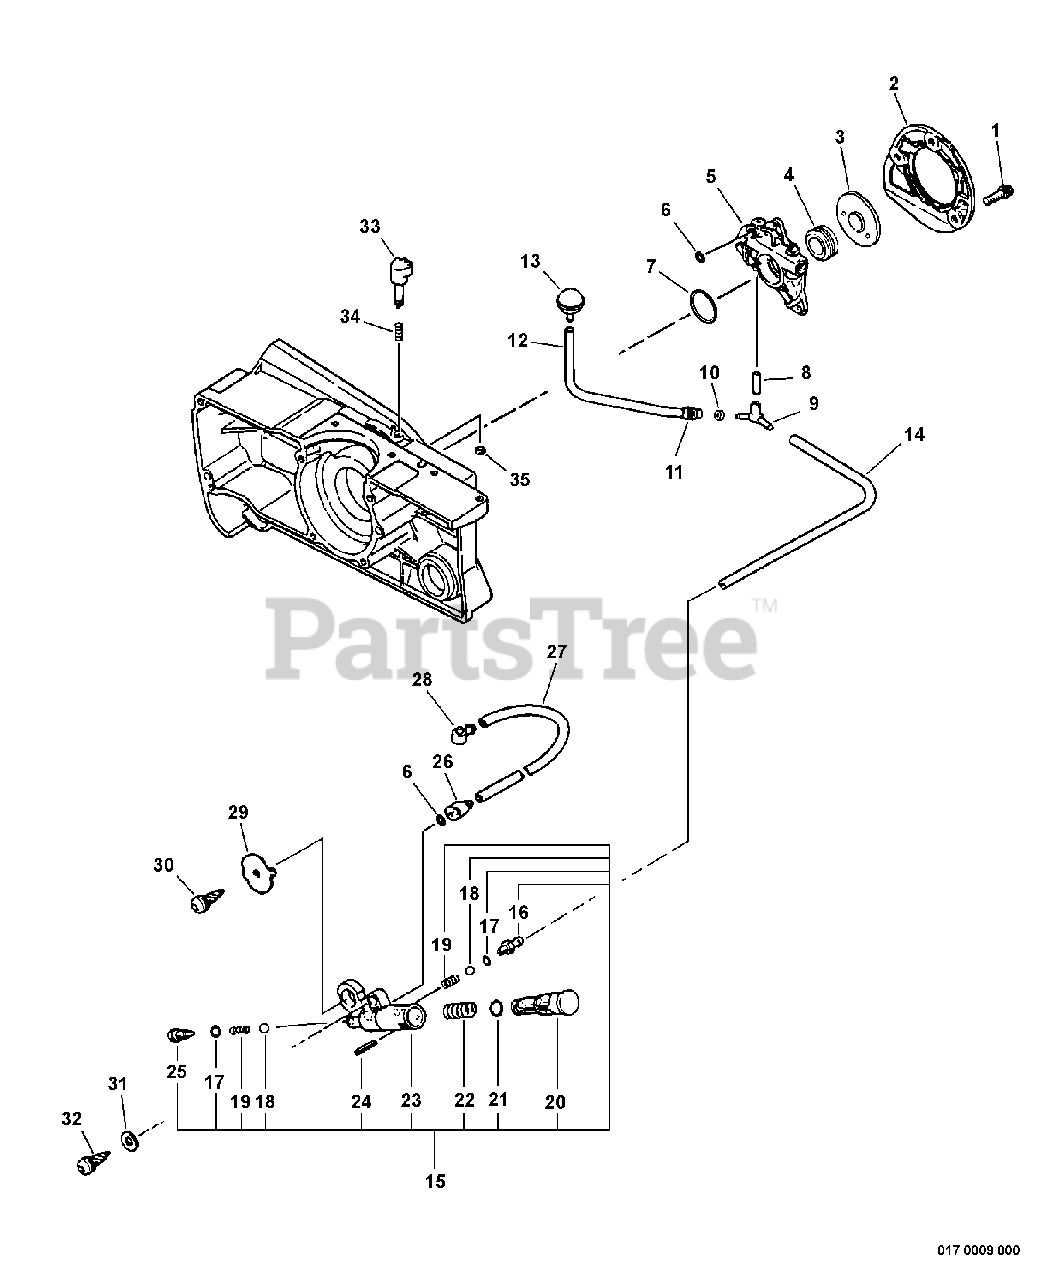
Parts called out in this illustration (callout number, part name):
1	SCREW - 4X12
2	COVER, OIL PUMP
3	WASHER - 12
4	GEAR - WORM
5	AUTO-OILER ASSY
6	O-RING - 3
8	PIPE - 3X6X20 -- BLACK
9	CONNECTOR, PIPE
10	CLIP - 6.5
12	PIPE - OIL
13	FILTER, OIL
14	PIPE - 3X6X200 -- BLACK
15	OIL PUMP ASSY
18	VALVE, BALL
20	PISTON, OIL PUMP
21	O-RING - 7
23	BODY, OIL PUMP
24	PIN - SPRING -- 2X16
25	ADAPTER, OIL PUMP
26	CONNECTOR, PIPE
27	PIPE, OIL - 3X6X125
28	CONNECTOR, PIPE
29	BRACKET, OIL PUMP
30	SCREW - 4X10
31	WASHER - 5
32	SCREW - 5X20
33	DIAL, AUTO-OILER
35	RING, RETAINING - 3
